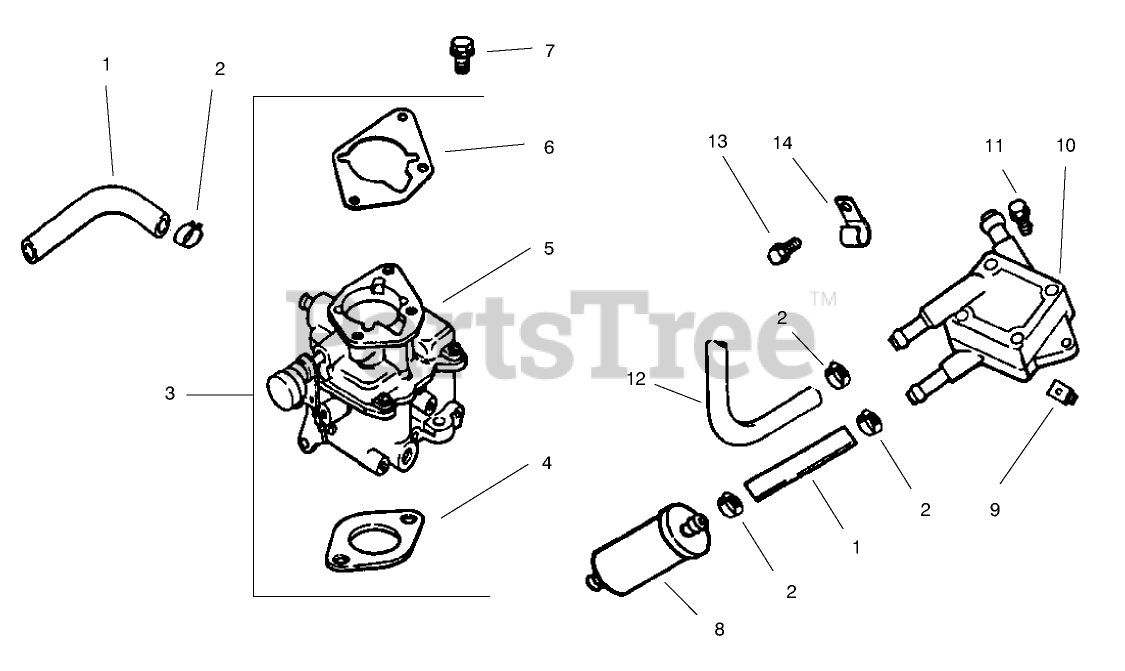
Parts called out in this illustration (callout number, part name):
1	Line fuel
2	Clamp
3	Kit, carburetor w/gasket (Includes 4-6)
4	Gasket
5	Carburetor assembly
6	Gasket
7	Screw
8	Filter-Fuel
9	Nut
10	Pump-Fuel
11	Screw
12	Line, fuel17"
13	Screw
14	Clamp
